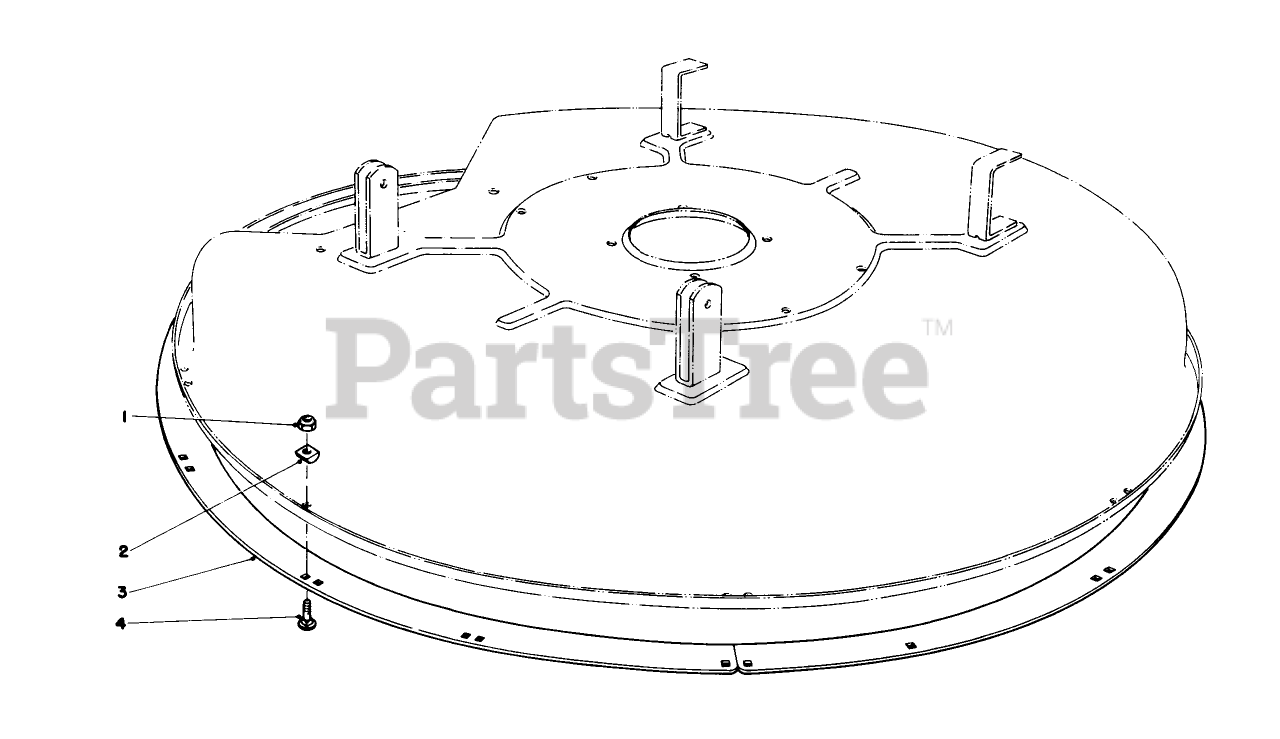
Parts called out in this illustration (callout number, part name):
1	NUT-LOCK, NI
3	DECK RING *B
4	BOLT-CARR
